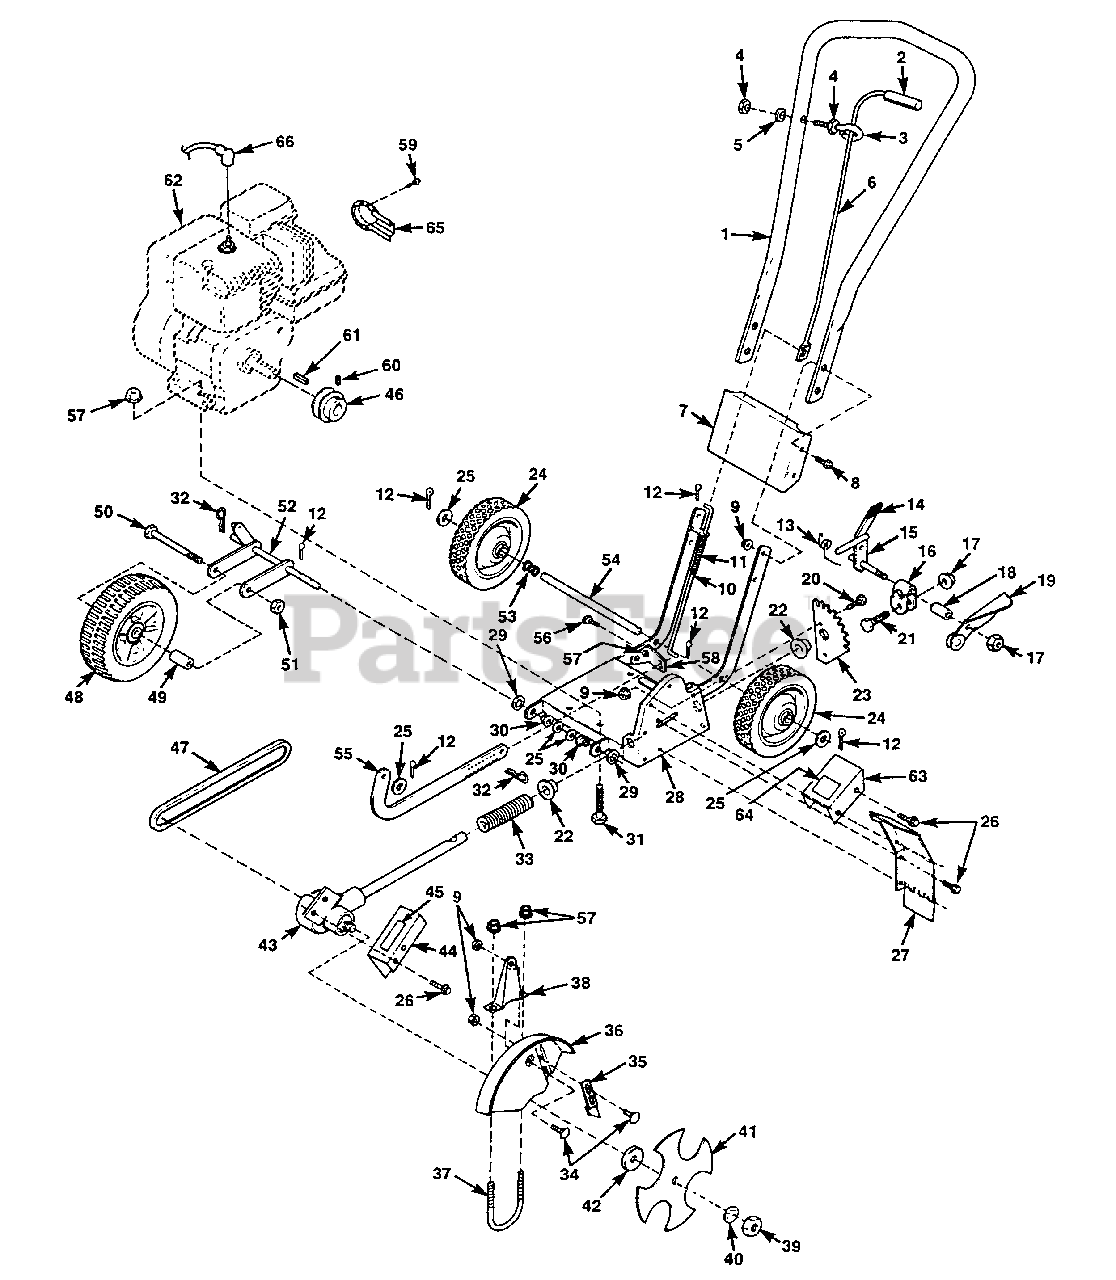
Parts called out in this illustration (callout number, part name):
1	HANDLE- Edger
2	GRIP- Depth Control
4	NUT- (1/4-20)
5	WASHER- Lock (1/4")
6	CONTROL- Depth
7	COVER- Handle
8	SCREW- Sems (1/4-20 x 1")
9	NUT- (1/4-20)
10	ROD- Lower Depth Control
11	SPRING- Depth Control
12	PIN- Cotter
13	SPRING- Angle Adjusting
14	GRIP- Angle Adjusting
15	LEVER- Angle Adjusting
16	CLAMP- Angle Adjusting
17	NUT- Hex lock
18	BUSHING- Angle Adjusting
19	LEVER- Clutch
20	SCREW- Sems hex hd.
21	SCREW- (3/8-16 x 1 1/4")
22	BUSHING- Nylon (3/4")
23	COMB- Angle Adjusting
24	WHEEL & TIRE
25	WASHER- Flat
26	SCREW- (1/4-20 x 1/2")
27	FLAP- Debris
28	FRAME- Main
29	RETAINER- Bushing
30	BUSHING- Nylon
31	SCREW- Cap hex hd.
32	PIN- Cotter hair
33	SPRING- Cutter head
34	BOLT- Carriage (1/4-20 x 5/8")
35	FINGER- Guide
36	GUARD- Blade
38	BRACKET- Blade Support
39	NUT- Jam (5/8-18)
40	WASHER- Lock (5/8")
41	BLADE- Star
42	WASHER- Dust Shield
43	HEAD- Cutter
44	GUARD- Cutter Pulley
45	DECAL- Warning
46	PULLEY- Engine
48	WHEEL- Front
49	SPACER- Axle
50	SCREW- (1/2-13 x 4")
51	NUT- Hex centerlock
52	BRACKET- Front wheel
53	SPRING- Axle
54	AXLE- Rear
55	RATCHET- Depth Control
56	SCREW- Hex hd.
57	NUT- Flanged (5/16-18)
58	BRACKET- Depth Control
59	SCREW- Hex hd.
60	SCREW- Set
61	KEY
62	ENGINE
63	GUARD- Engine Pulley
64	DECAL- Safety
65	DEFLECTOR
66	TERMINAL- Hi-Tension
